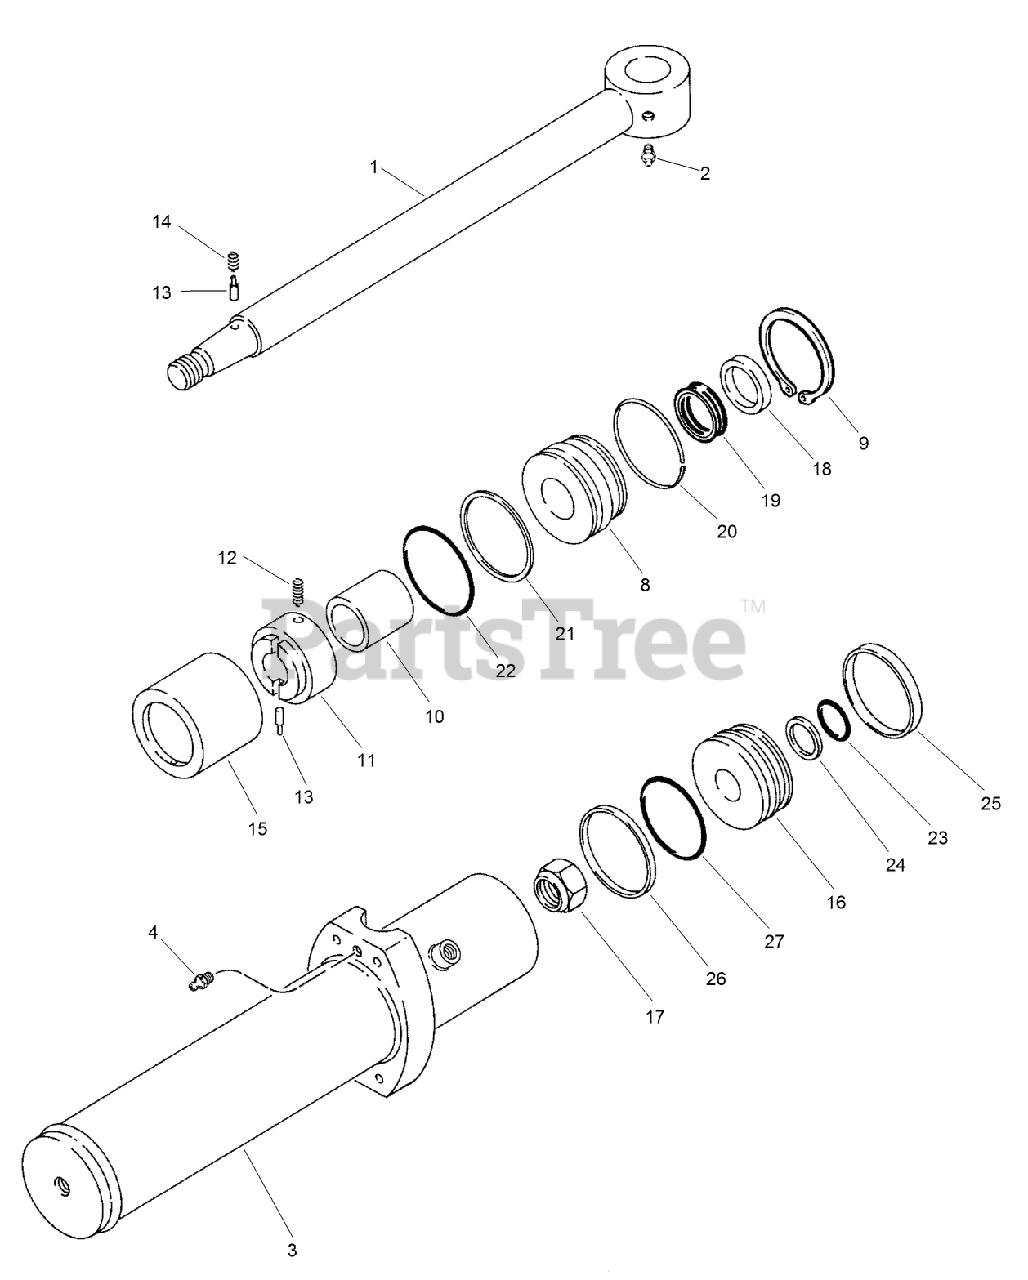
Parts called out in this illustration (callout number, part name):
1	ROD - Piston
2	FITTING - STR Grease 3/16
3	TUBE - Cylinder
4	FITTING-Lube 1/8-27 Dryseal PTF
8	GLAND - Cylinder
9	RING - Retaining
10	SPACER
11	RETAINER
12	SPRING
13	PIN - Lock
14	SPRING
15	SLEEVE - Cylinder
16	PISTON - Cylinder
17	NUT - 1-1/8
18	WIPER - Piston Rod
19	SEAL - Rod
20	RING - Lock
21	RING-backup, gland O-ring
22	O-RING-3 ID x 1/8 inch wide, gland
23	O-RING - Piston - 1-3/16 ID x 1/8
24	RING - Backup
25	RING - Wear, Piston
26	WASHER - Backup
27	O-RING - Piston
